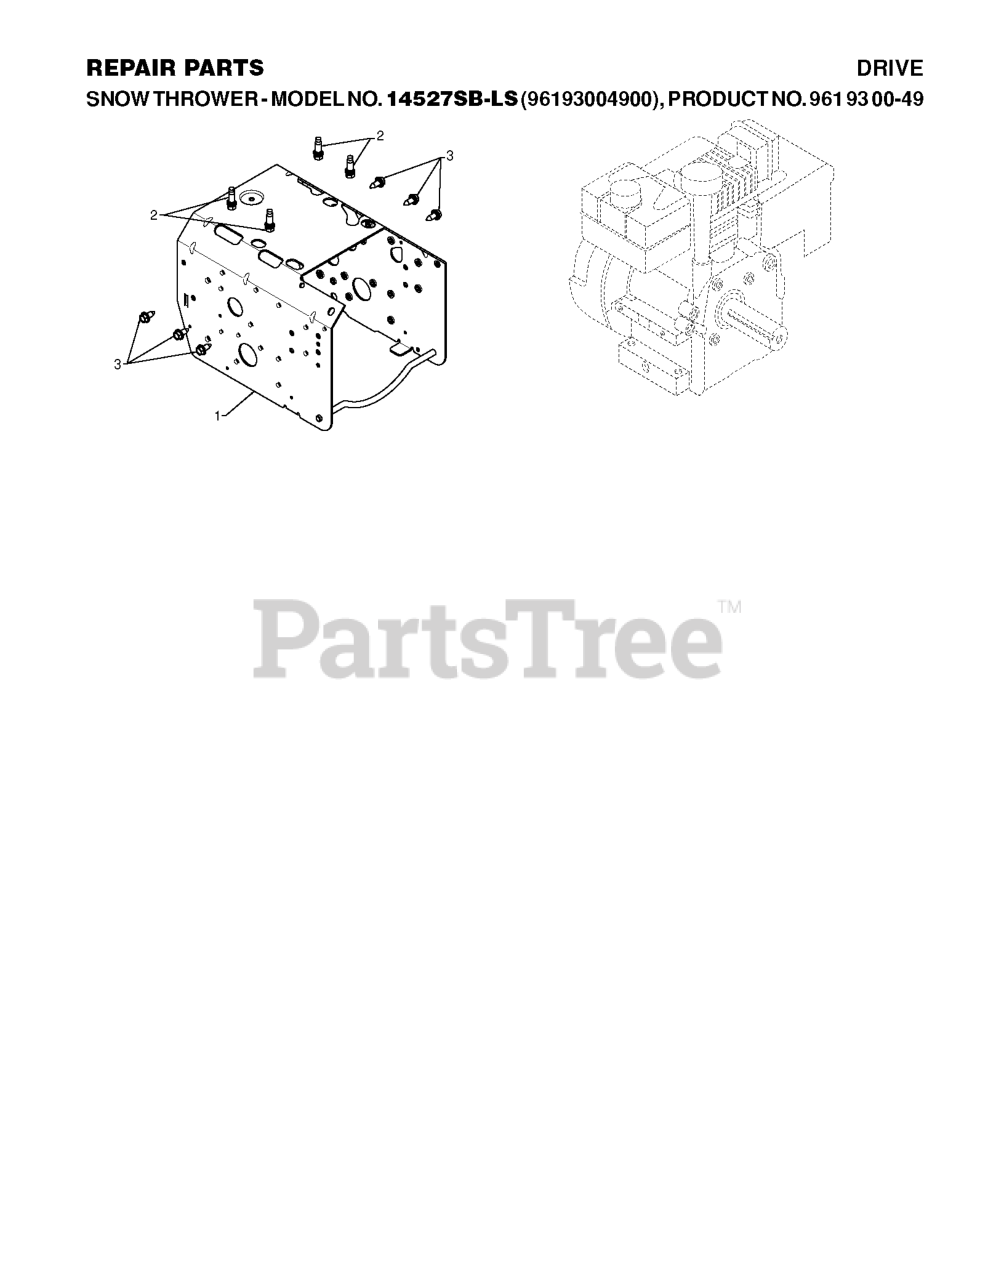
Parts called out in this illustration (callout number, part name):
1	FRAME.WELD.PNT.GEAR.ORANGE
2	BOLT 3/8-16X1-1/8
3	BOLT.HEX.HD.WASHER.5/16-18X.75
